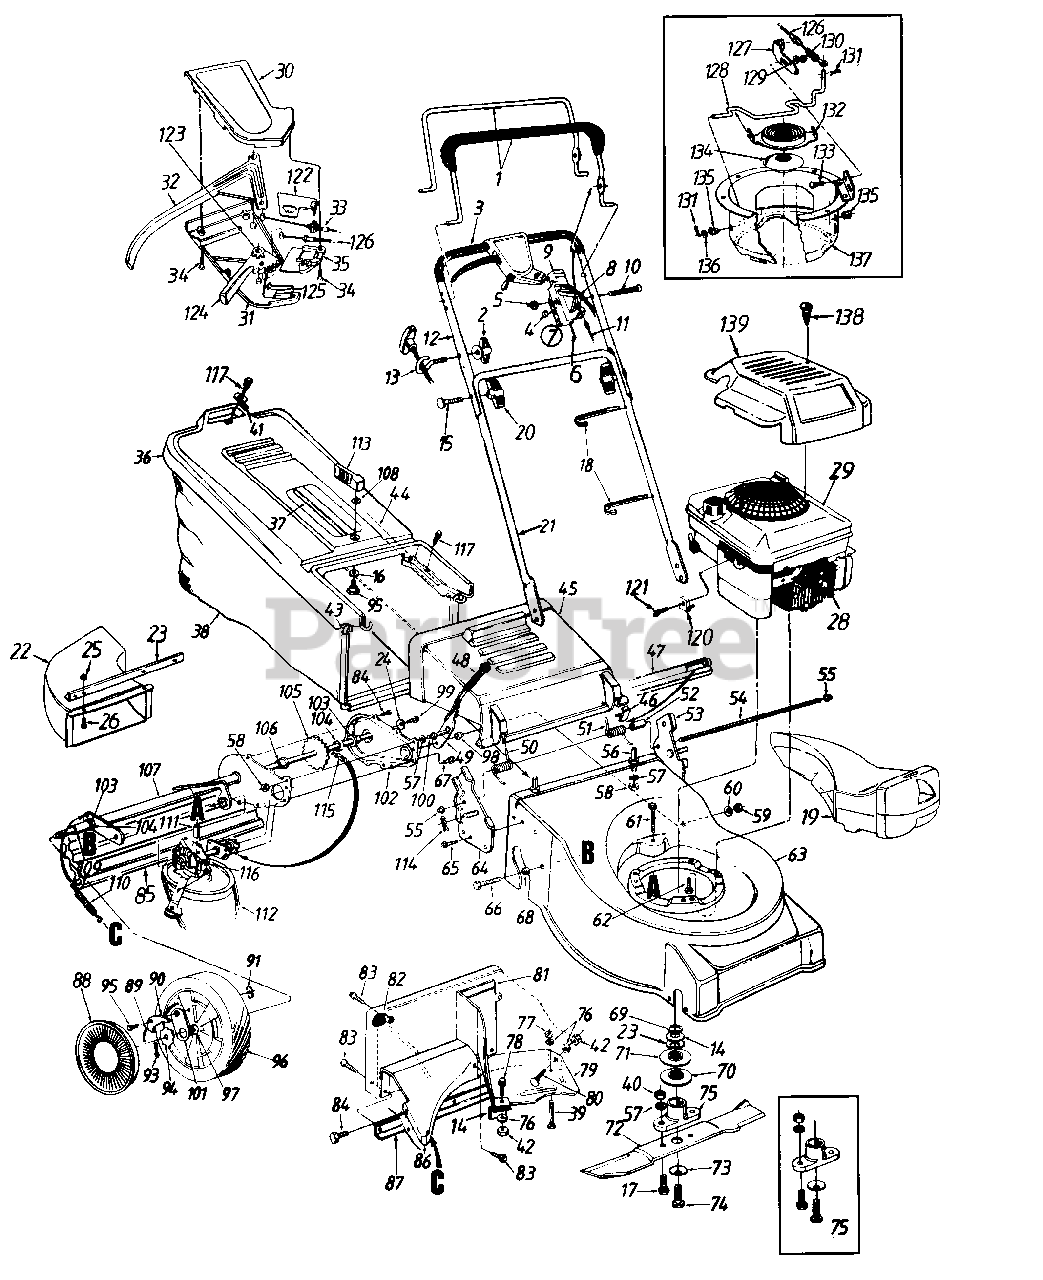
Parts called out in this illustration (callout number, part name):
2	Handle Knob 1/4-20 Thd.
3	Foam Grip
4	Spr. Wash. .66" I.D.
5	Hex L-Nut 1/4-20 Thd.
6	Throttle Cable-55" (B&S)
7	Throttle Box Comp.
8	Throttle Lever
9	Throttle Body
10	Oval C-Sunk Scr.
11	Control Cable-40.5" (B&S)
13	Rope Guide
14	Stop Bracket
15	Curved Hd. Bolt 5/16-18 x 2"
16	Bowed Washer
17	Hex Bolt 3/8-24 x 1" Lg.
18	Cable Tie
19	Mulching Plug
20	Hand Knob
22	Chute Deflector
24	Bell-Wash. .265" I.D. x .75"
25	Hex L-Nut 1/4-20 Thd.
26	Mach, Scr. 1/4-20 x .5" Lg.
28	Spark Plug Boot
29	Engine
30	Control Cover Half-Upper
31	Control Cover Half-Lower
32	Control Lever
33	Drive Cable-51" Lg.
34	Flat C-Sunk Hd. Tap Scr. #10 x .75" Lg.
35	S.P. control Cover
36	Hardtop Bag Cover
37	Hardtop Handle
38	Grass Bag
39	Truss Mach. Scr. 1/4-20 x 1.0" Lg.
40	Hex Nut 3/8-24 Thd.
41	FL-Wash. .281" I.D. X .62"
42	Hex Nut 1/4-20 Thd.
44	Rear Catcher Frame
45	Chute Deflector
46	Deflector Plug
47	Seal-Extrusion
49	Spring Lever
50	Torsion Spring-R.H.
51	Torsion Spring-L.H.
52	Spacer .255" I.D.
55	Cap Speed Nut
56	Shld. Pin 3/8-24 x 1.43" Lg.
57	L-Wash. 3/8" I.D.
58	Hex Jam Nut 3/8-24 Thd.
59	Hex L-Nut 3/8-24 Thd.
60	Bell-Wash. .38" I.D. x .88"
61	Hex Wash. Hd. Tap Scr. 1/4-20 x 1.5" Lg.
62	Hex L-Wash. Hd. Scr.3/8-16 x 1" Lg.
63	21" Deck Ass'y.
66	Hex Wash. Hd. Tap Scr. 3/8-16 x .75" Lg.
67	Hex Wash. Hd. Tap Scr. 1/4-20 x .5" Lg.
68	Spacer .383" I.D.
69	Crankshaft Spacer (Keyed)
72	21" Blade
73	Bell-Wash. .46" I.D.
74	Hex Bolt 7/16-20 x 1.5" Lg.
75	Blade Adapter Kit
76	L-Wash. 1/4" I.D.
77	Hex Jam Nut 1/4-20 Thd.
78	Hex Bolt 1/4-20 x .85" Lg.
83	Torx Mach. AB-Tap Scr. 1/4 x .62" Lg.
84	Hex B-Tap Scr. 1/4 x .38" Lg.
85	Rear Flap
88	Hub Cap Gray (5-1/2" Dia.)
88	Hub Cap Beige (5-1/2" Dia.)
89	Plastic Spring
90	Pawl .345" I.D.
91	Weld Top L-Nut 1/4-20 Thd.
93	Cotter Pin 1/8" Dia.
94	Ratchet Wheel 1.62" O.D.
95	Shld. Bolt .342" Dia. x .268"
96	Wheel Ass'y. Comp.-Rear
97	Bearing 1/2" I.D.
98	Shld. Spacer .50" Dia.
99	Hex Bolt 1/4-20 x .62" Lg. (Gr. 5)
100	Shld. Pin 3/8-24 x 1.43" Lg.
101	Pawl Plate
104	FL-Wash. .531" I.D. x .93"
105	Rear Axle Ass'y
106	Hex Flange Bearing
109	Spacer .513" I.D.
110	Extension Spring 3.8" Lg.
111	Spacer .325" I.D.
112	V-Belt
113	Grass Catcher Locking Knob
114	Internal Cotter Pin 5/16" Dia.
115	#48 Chain .50" Pitch x 30 Links
116	Transmission Comp.
117	Hex L-Wash. H.D. AB-Tap Scr.
120	Cable Clamp (B&S)
121	Hex Self-Tap Scr. #10-32 x .62" Lg. (B&S)
122	6-Speed Rack Cable Brkt.
123	3 Tooth Rack Gear Insert
124	6-Speed Shift Lever
125	Shift Lever Spring
126	Spd. control Cable
129	Bell-Wash. .265" I.D. x .75"
130	Hex Cent. L-Nut 1/4-20 Thd.
131	Cot-Pin 3/32" Dia. x .75" Lg.
132	Movable Pulley Half Ass'y.
133	Carr. Bolt 1/4-20 x .5" Lg.
134	Splined Pulley Half
135	Flanged Bushing
136	FL-Wash. .328" I.D. x .68" O.D.
139	XTE Engine Shroud (Red)
